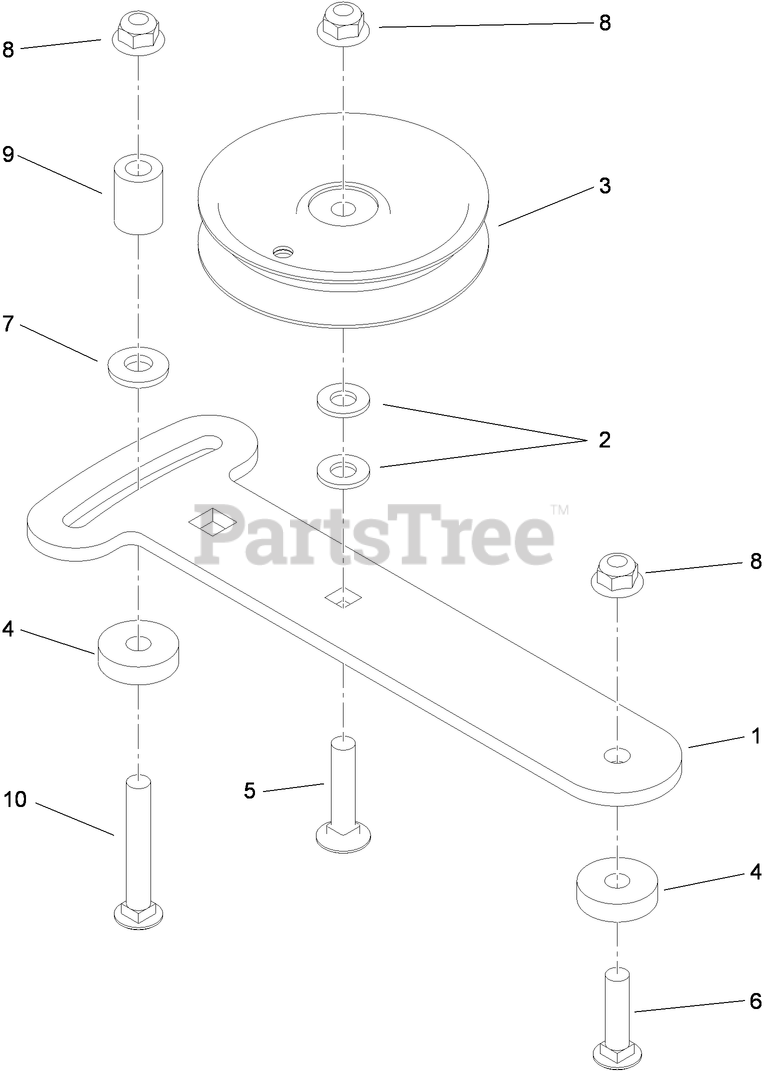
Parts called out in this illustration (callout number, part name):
1	PLATE-IDLER
2	WASHER-FLAT
3	PULLEY-IDLER
4	Spacer
5	SCREW-CARR
6	SCREW-CARR
7	WASHER-BELLEVILLE
8	NUT-HF, NI
9	TUBE-INTERLOCK
10	SCREW-CARR
